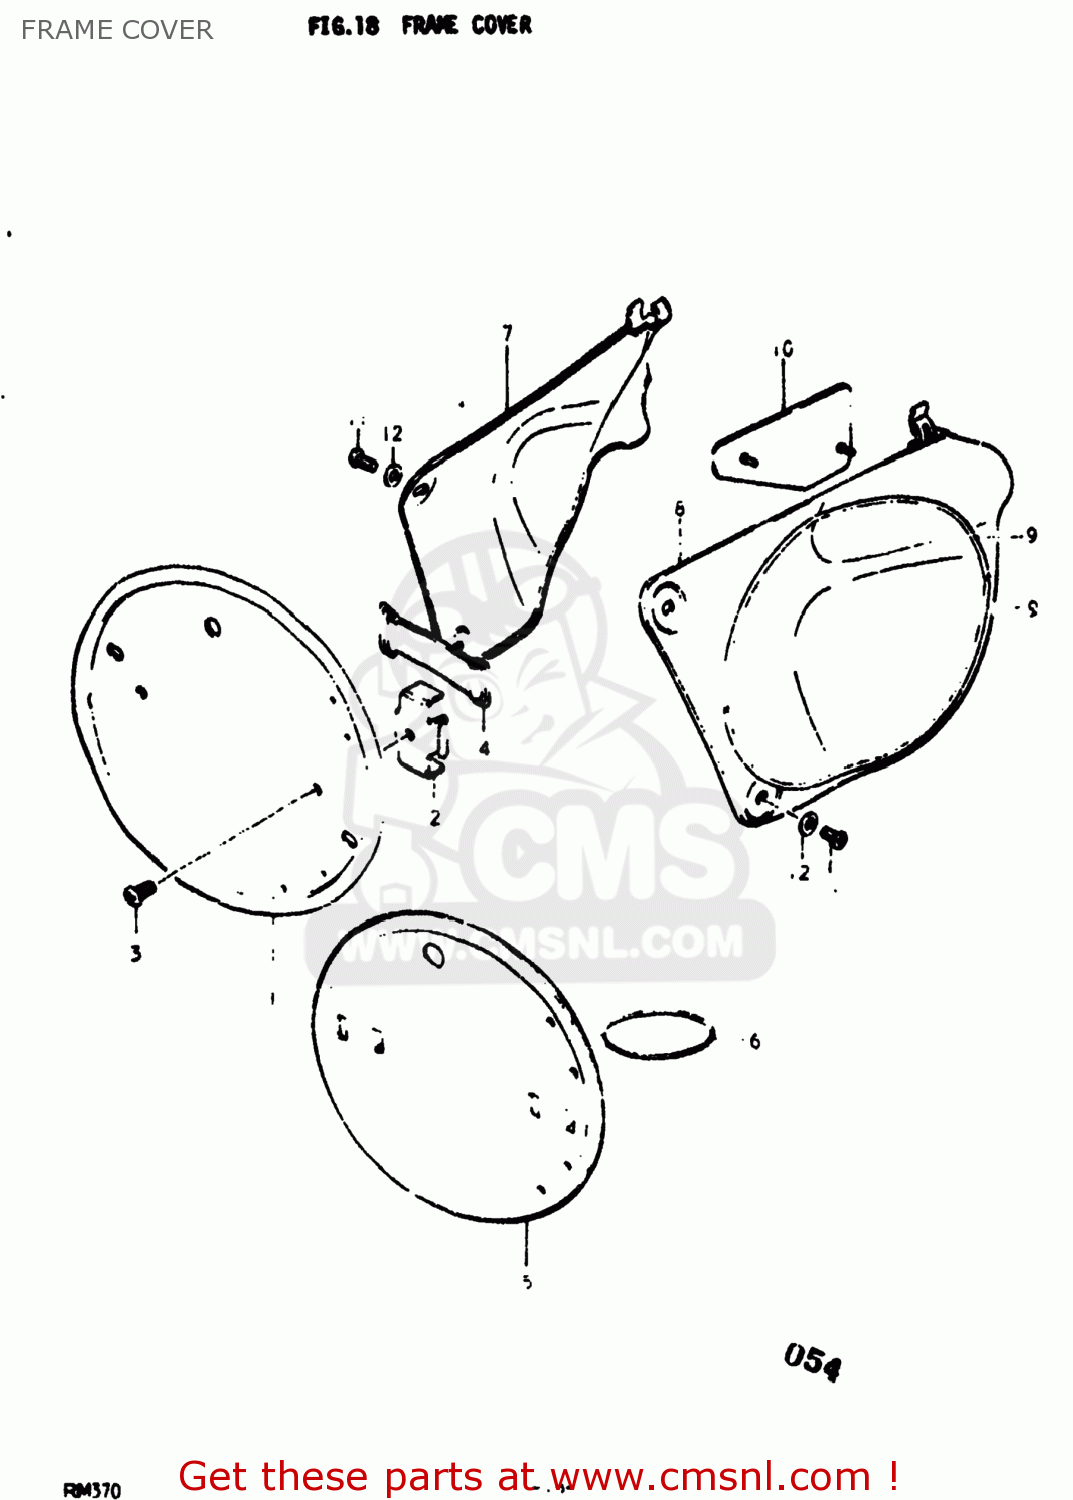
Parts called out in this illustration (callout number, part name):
1	PLATE SET,FRONT
3	SCREW 6X12
4	BAND
5	PLATE,NUMBER,FRONT
6	O-RING
7	COVER,FRAME,RIGHT
8	COVER,FRAME,LEFT
9	TAPE,FRAME COVER
11	SCREW 6X12
12	WASHER
